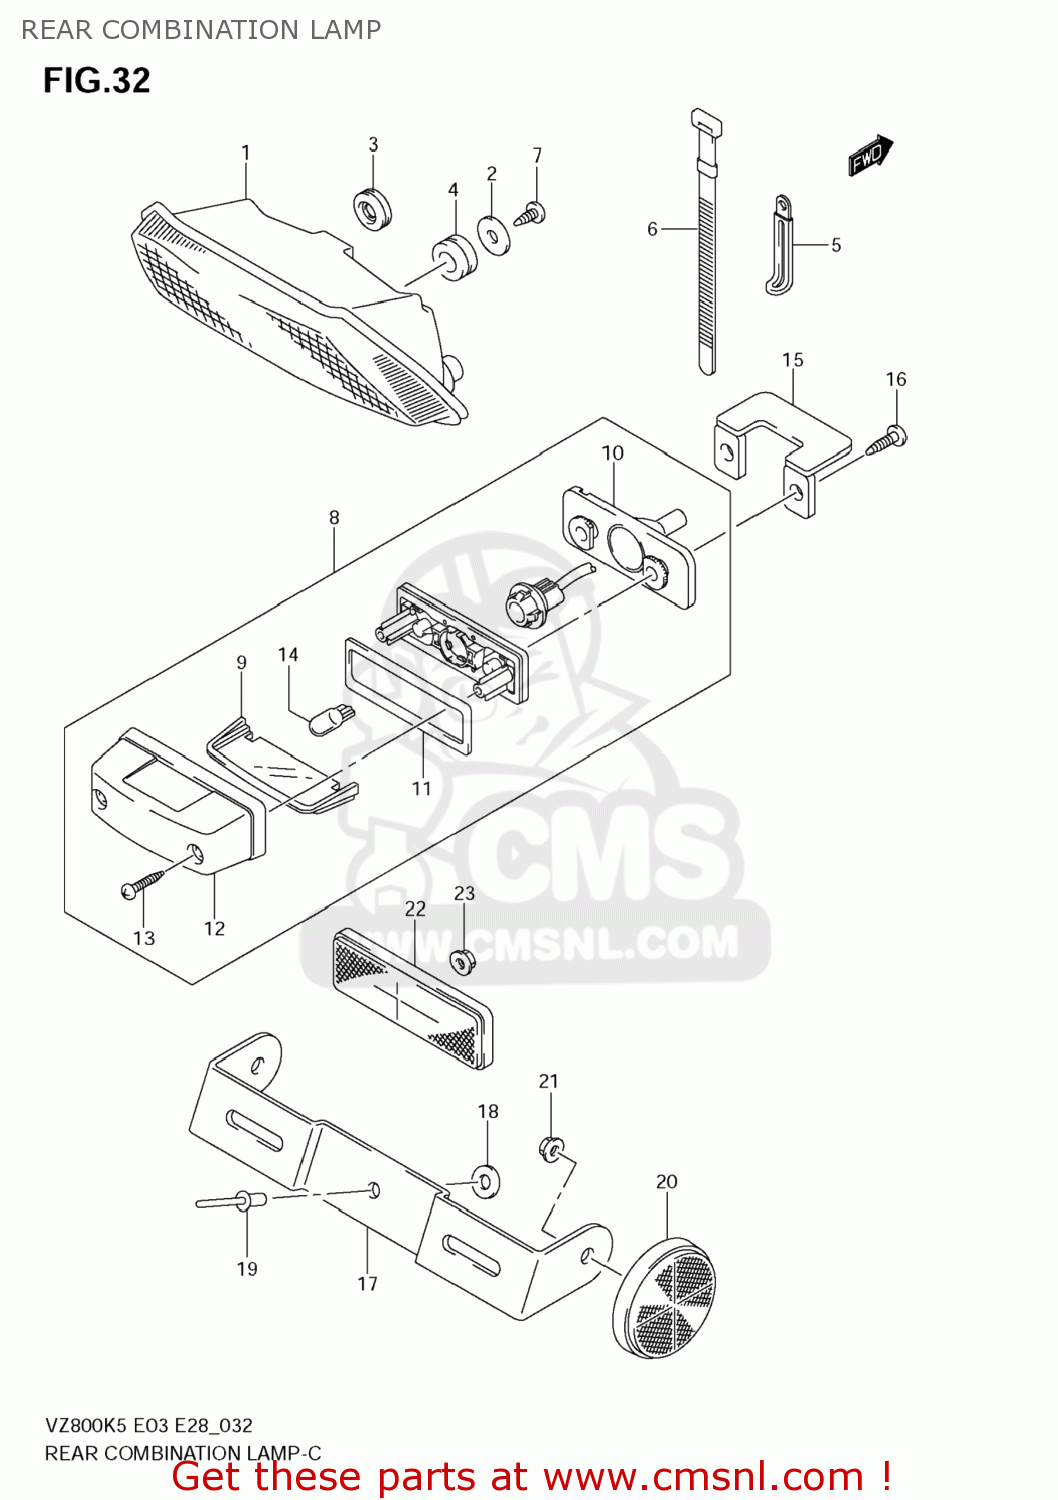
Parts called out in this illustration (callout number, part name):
1	LAMP ASSY,RR COMBINATION
2	WASHER(5.5X20X1.2)
3	GROMMET
4	CUSHION
5	CLAMP(L:45)
6	CLAMP(L:125)
7	SCREW
8	LAMP ASSY,LICENSE
9	LENS
10	CUSHION
11	GASKET (NAS)
12	COVER
13	SCREW
14	BULB(12V5W)
15	BRACKET,LICENSE
16	SCREW
17	BRACKET,LICENSE PLATE
18	WASHER(5.5X18X1)
19	RIVET
20	REFLECTOR ASSY,RR SIDE
21	NUT
22	REFLECTOR ASSY,RR
23	NUT
